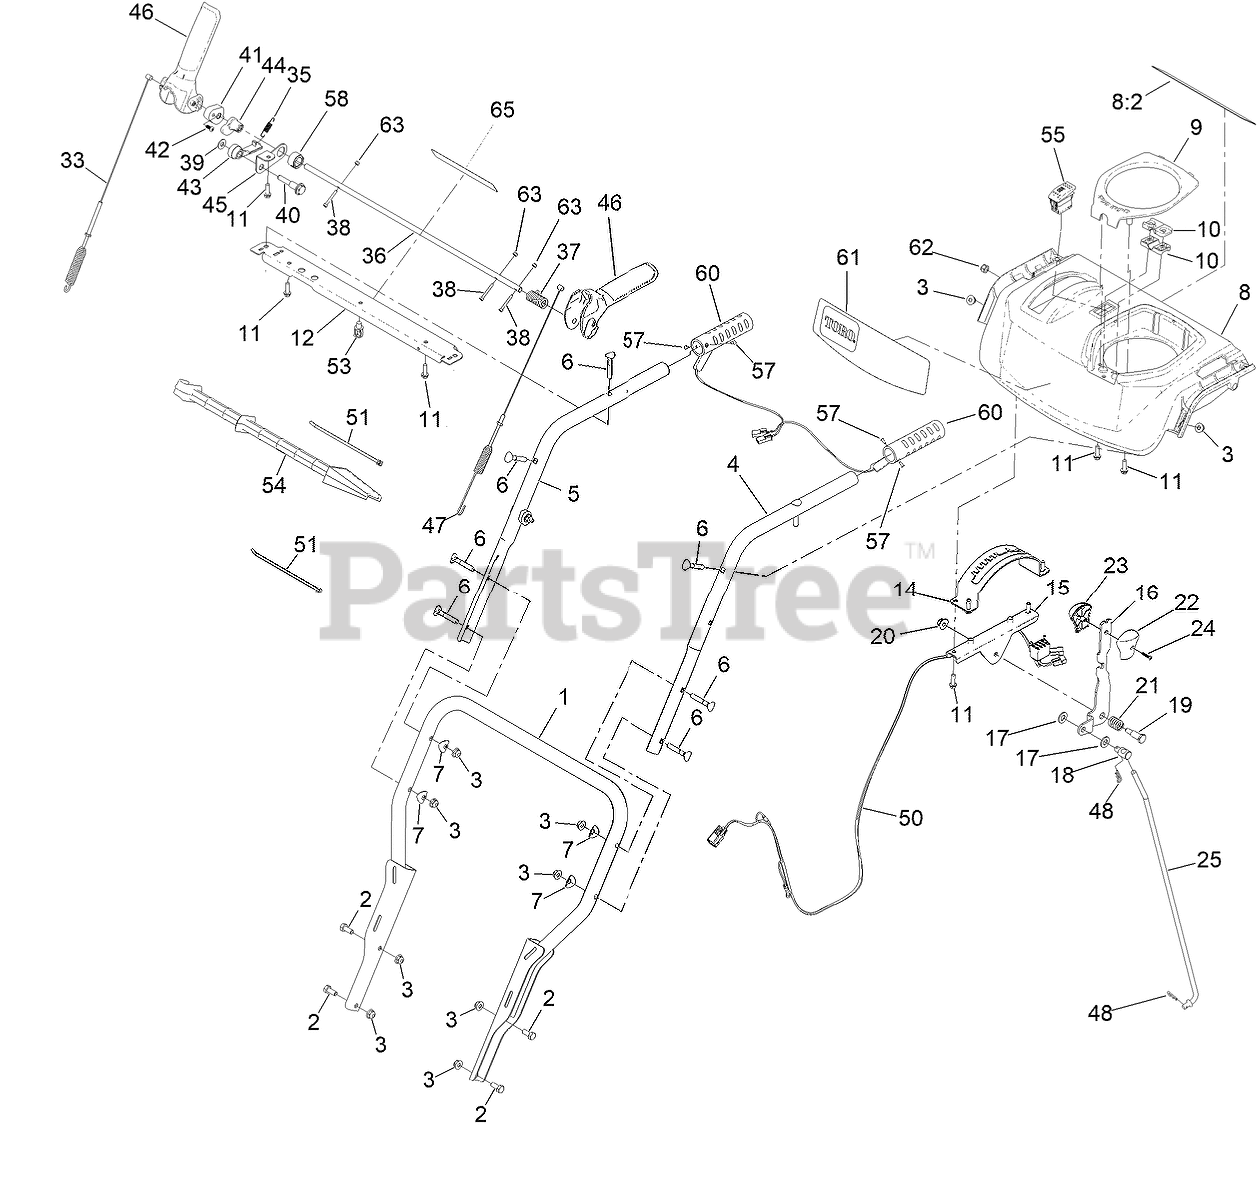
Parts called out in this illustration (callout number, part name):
1	LOWER HANDLE ASM
2	SCREW-HH
3	NUT-HF
4	HANDLE-UPPER, LH
5	HANDLE-UPPER, RH
6	SCREW-HANDLE
7	WASHER-CUP
8	PANEL-CONTROL, W/GRAPHICS
8:2	DECAL-SAFETY
9	COVER-QUICKSTICK
10	SUPPORT-ROD
11	SCREW-PLASTITE, HWH
12	BRACE-CONSOLE
14	GATE-SHIFT
15	BRACKET-SHIFT
16	SELECTOR-SPEED
17	WASHER-FLAT
18	TRUNNION-ROD
19	SCREW-SHOULDER, HH
20	NUT-HF
21	SPRING-COMPRESSION
22	KNOB-SHIFT, LH
23	KNOB-SHIFT, RH
24	SCREW-PPH
25	ROD-SHIFT
33	CABLE-AUGER
35	SPRING-LOCKOUT, HANDLE
36	ROD-LOCKOUT
37	SPRING-TORSION, HANDLE RETURN
38	SCREW-HSH
39	WASHER-FLAT
40	SCREW-SHOULDER
41	LOCK-HANDLE
42	SCREW-PPH
43	LATCH-LOCKOUT
44	CAM-LOCKOUT
45	LINK-LOCKOUT
46	LEVER-CONTROL
47	CABLE-TRACTION
48	PIN-HAIR
50	HARNESS-WIRE, LED AND HAND WARMERS
51	TIE-CABLE
53	CLIP-TIE
54	STICK-CLEANOUT
55	SWITCH-ROCKER, ON-NONE-OFF (HEATER)
57	RIVET-POP
58	COLLAR-CAM
60	GRIP-HEATED
61	DECAL-CONSOLE
62	NUT-HEX
63	NUT-HHF
65	DECAL-HYDRO
